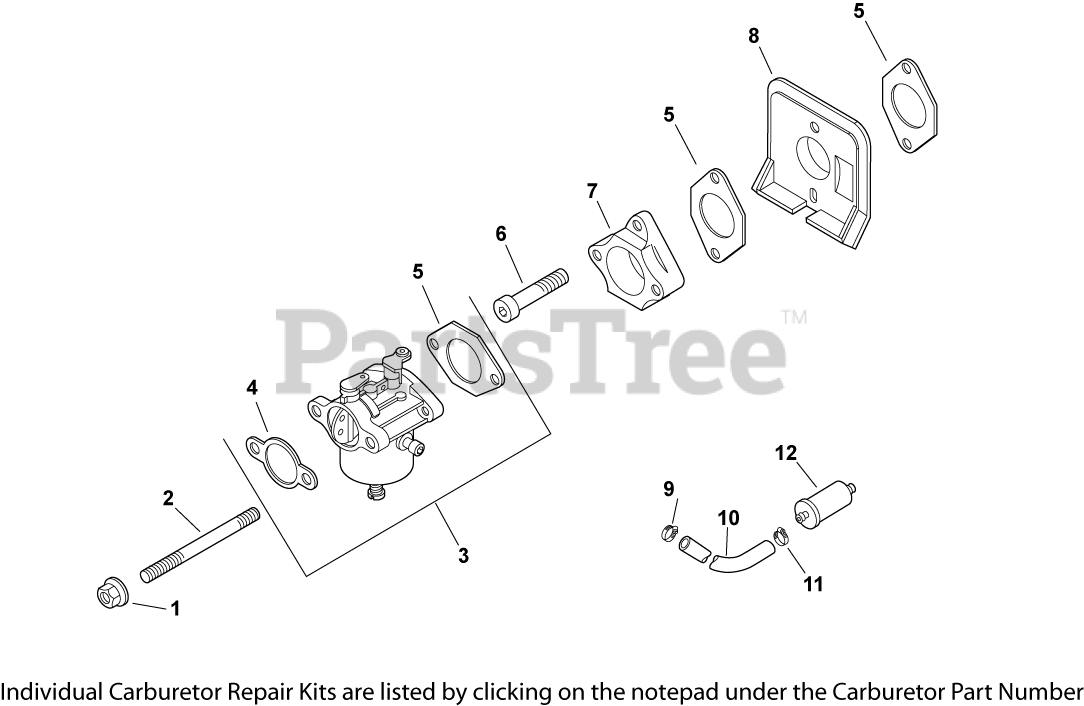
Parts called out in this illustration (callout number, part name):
1	NUT, FLG M6X1.0
2	STUD,M6X1.0X116
3	KIT, CARB W/GASKETS - USE 12 853 177-S
4	GASKET, AIR CLEANER BASE
5	GASKET, CARBURETOR
6	SCREW, SKT CAP M6X1.0X35
7	ADAPTER, CARBURETOR
8	DEFLECTOR, HEAT
9	CLAMP, HOSE (KM)-USE 25 237 31-S
10	HOSE,LW PERM.FUEL 24.00"-USE 25 111 81-S
11	CLAMP, BAND SPRING HOSE-(#2523737S)
12	FILTER, FUEL
